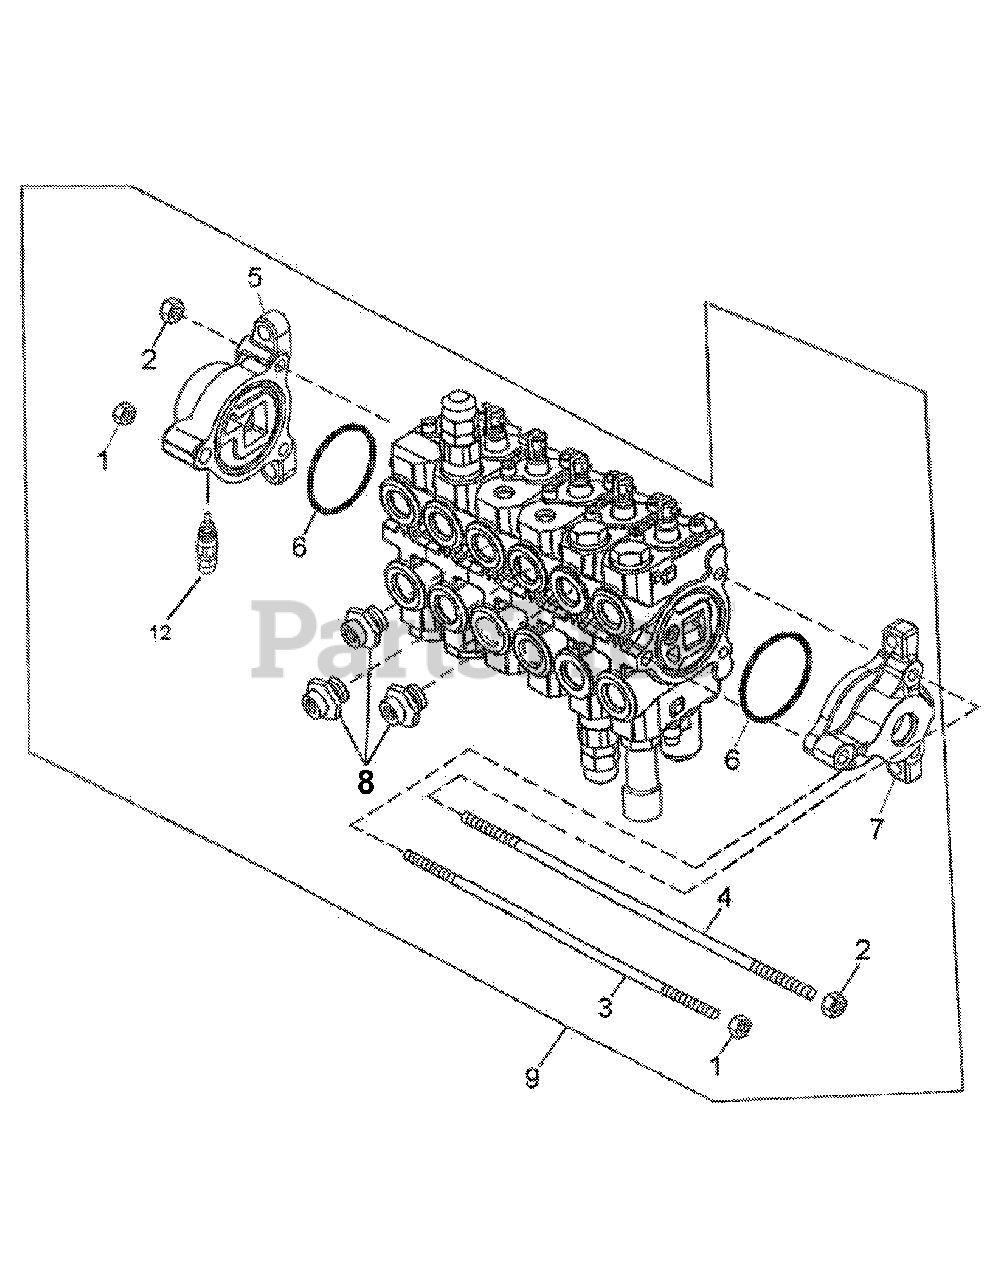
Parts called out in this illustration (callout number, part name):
1	Nut, 3/8
2	Nut, 5/16"
3	Tie Rod
4	Tie Rod
5	Outlet Cover
6	O-Ring, Section Seal
7	Inlet Cover with O-Ring
8	Restrictor Assembly - .073" Diameter
9	Control Valve Assembly
10	Tie Rod Kit
11	Valve Seal Kit
12	Main Relief - 2550 PSI
13	Main Relief Spring and Seal Kit
14	Main Relief Seal Kit
